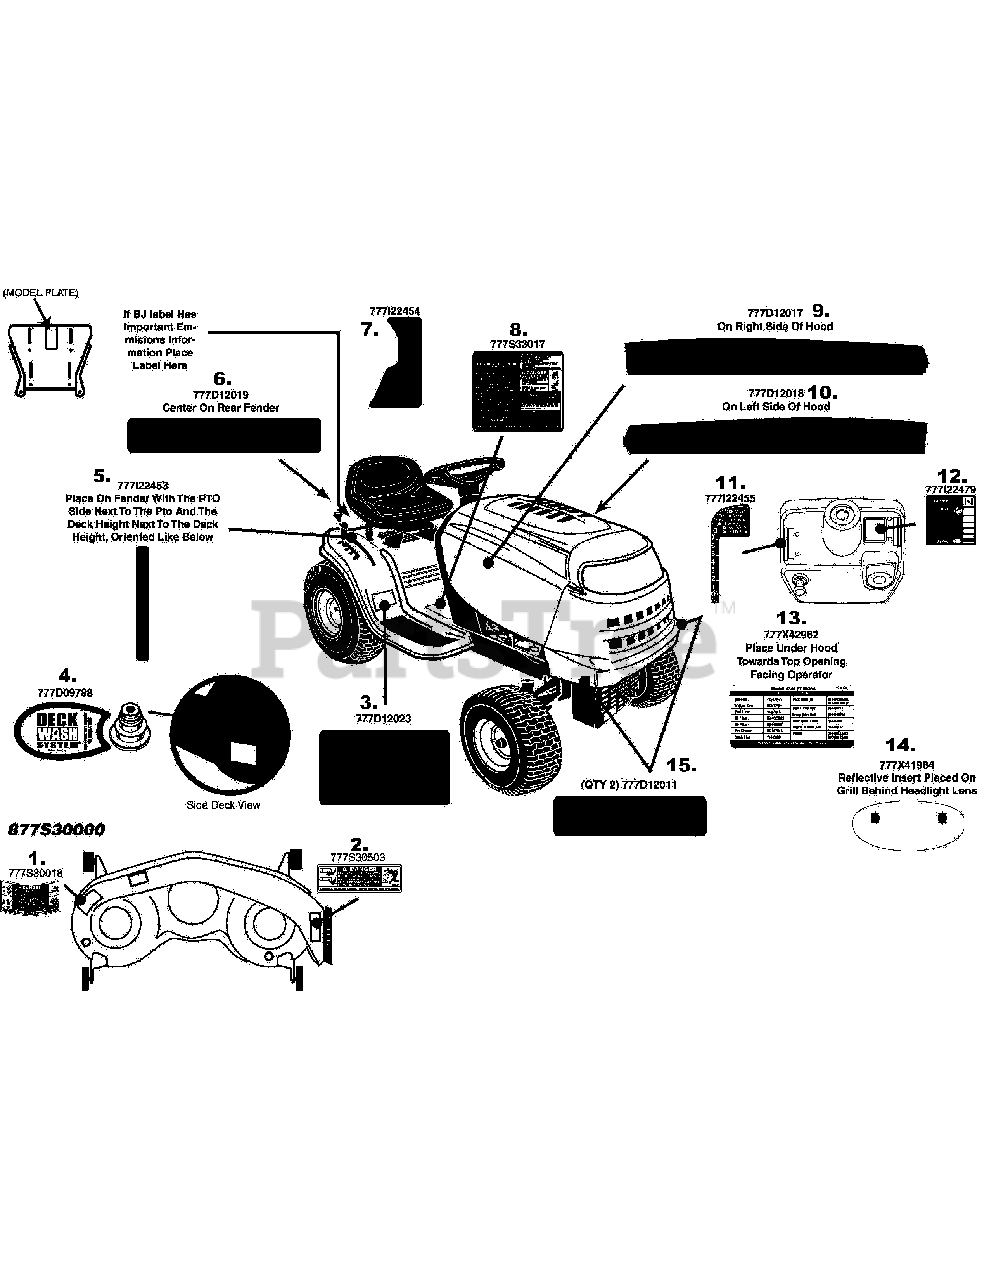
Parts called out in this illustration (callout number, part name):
1	LABEL-DECK SAFETY
2	LABEL-DANGER CHUTE
3	LABEL-RIDER FENDER 46" 7SPD
4	LABEL:RIDER:WHITE
5	LABEL:RIDER LT-5 FENDER
6	LABEL-RIDER REAR FENDER MTD GOLD
7	LABEL:RIDER LT-5 FENDER
8	LABEL-LT 5 TRANS COVER NO OCR
9	LABEL-RIDER HOOD MTD GOLD RH
10	LABEL-RIDER HOOD MTD GOLD LH
11	LABEL:RIDER LT-5 DASH
12	LABEL: RIDER LT-5 THRT/CHK
13	LABEL-RIDER PARTS LIST L771H004
14	LABEL:RIDER 1&5 STYLE GRILL
15	LABEL-RIDER LOWER GRILLE CAST IRON
